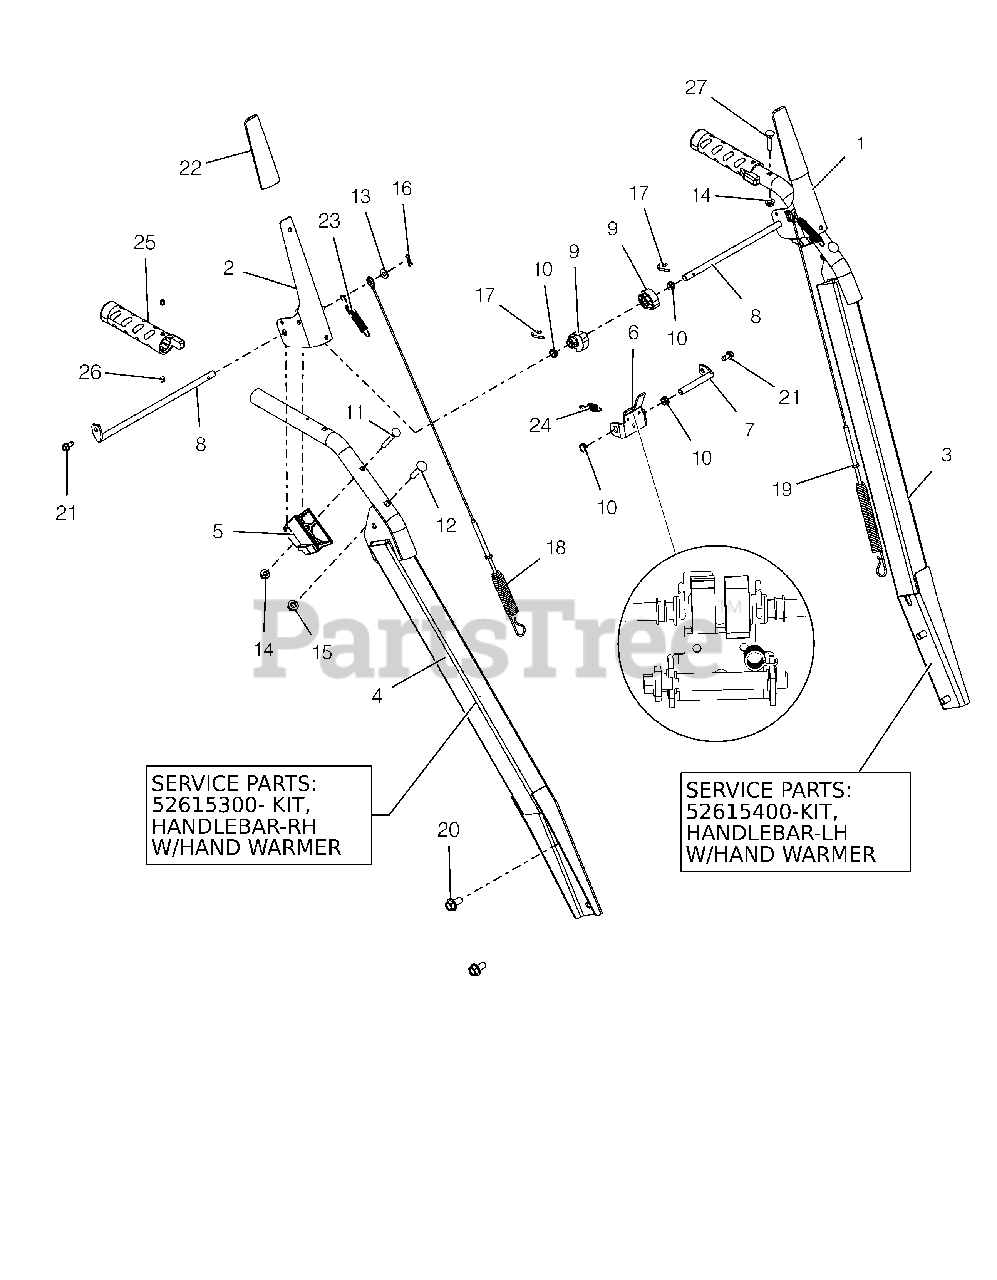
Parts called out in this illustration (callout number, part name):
1	LEVER, CLUTCH-LH
2	LEVER, CLUTCH-RH
3	HANDLEBAR, HEAVYDUTY-PRO LH
3	KIT, HANDLEBAR-LH W/WARM GRIP
4	HANDLEBAR, HEAVYDUTY-PRO-RH
4	KIT, HANDLEBAR-RH W/WARM GRIP
5	BLOCK, CLUTCH PADDLE
6	BRACKET, INTERLOCK ARM
7	ROD, INTERLOCK PIVOT
8	ROD, PADDLE MOUNT - PRO
9	CAM, INTERLOCK
10	BUSHING, POLYLINER-.38 SNAPIN
11	BLT-RDHDXLSQNK .25-20X2.0 G5YZ
12	@BLT-RDHDSQNK .31-18X1.50 G5YZ
13	@WSHR-FL-STL.281X.62X.065 YWZC
14	NUT-LK-CTR-FLG .25-20 YWZC
15	@NUT-LK-TOP-FLG .31-18 YWZC
16	PIN-HAIR INT .06X.18X.77
17	PIN, SPRING CLIP
18	CABLE, AUGER (DELUXE & PRO)
19	CABLE, UPPER TRACTION
20	BLT-SERHFWH .38-16X.75 YWZC
21	SCR-TAP .25-20X.50 HWH TR YWZ
22	SLEEVE, CLUTCH PADDLE-GRAY
23	SPRING, EXTENSION
24	SPRING-EXT .047X.438X1.45
25	GRIP,HEATED HANDLE-GRAY
26	RVT-POP #43 .125X.313 STL ZINC
27	BLT-RDHDXLSQNK.25-20X1.25 G5ZC
